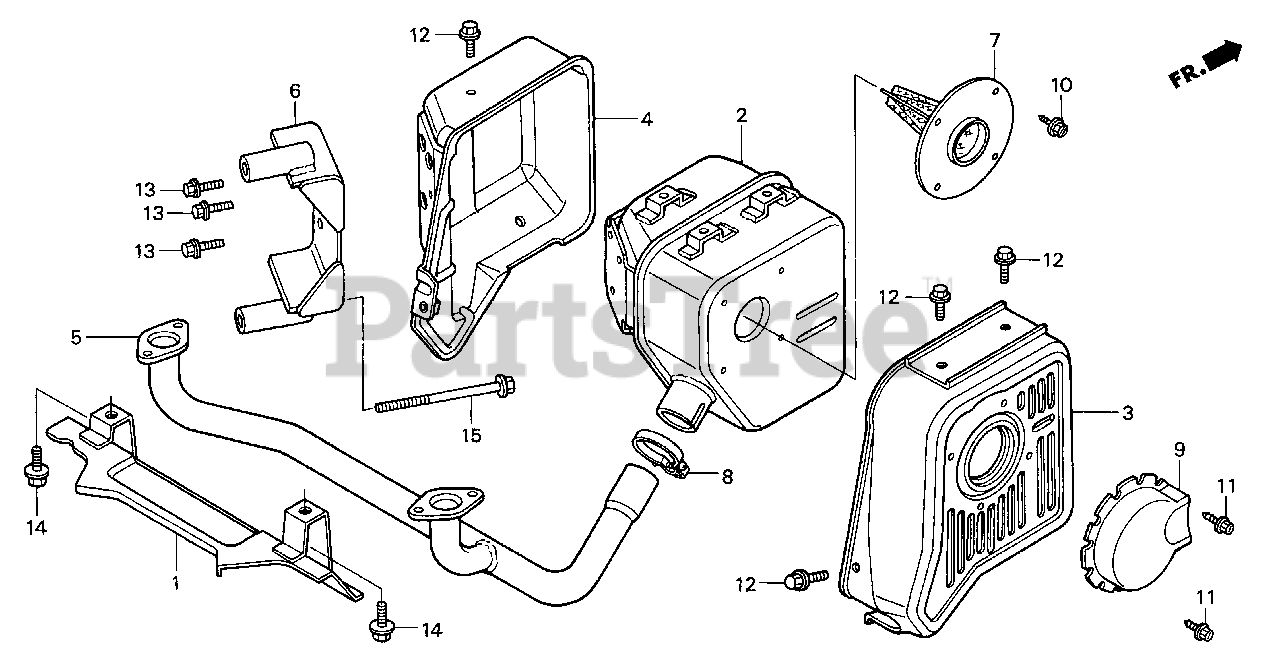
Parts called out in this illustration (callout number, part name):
1	PROTECTOR, EX. PIPE
2	MUFFLER
3	PROTECTOR, MUFFLER (SIDE-L)
4	PROTECTOR, RR. MUFFLER
5	PIPE, EX.
6	STAY, MUFFLER
7	ARRESTER, SPARK (SIDE)
8	BAND ASSY.
9	DEFLECTOR KIT, EX.
10	SCREW (NELSON)
11	SCREW, TAPPING (4X8)
12	BOLT, FLANGE (6X8)
13	BOLT, FLANGE (6X12)
14	BOLT, FLANGE (8X16)
15	BOLT, FLANGE (8X80)
